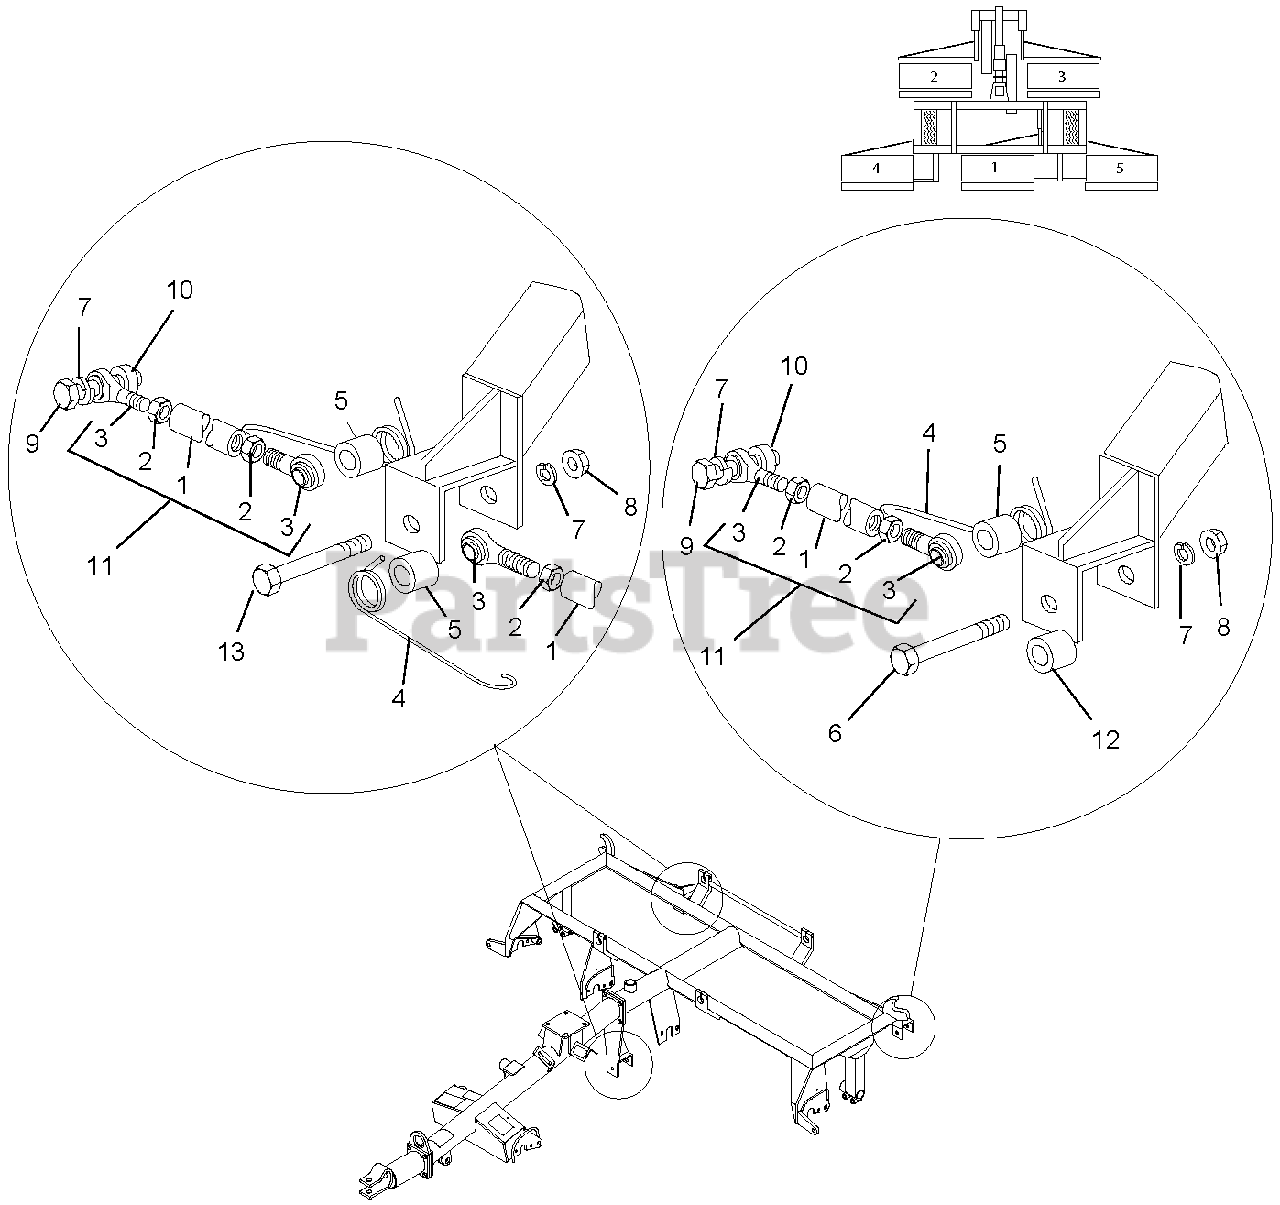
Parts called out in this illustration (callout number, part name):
1	Tie Rod, Rear
2	Nut, Hex .625-18 Right-Hand Thread
3	Rod End, .625 Bore, Left-Hand Thread
4	Spring, Compensator .25
5	Spacer, Compensator Long
6	Cap Screw, Hex Head .625-11 x 3.75
7	Washer, Lock .625
8	Nut, Hex .625-11
9	Cap Screw, Hex Head .625-11 x 2
11	Tie Rod Assembly, Short
12	Spacer, Compensator Short
13	Cap Screw, Hex Head .625-11 x 4.75
